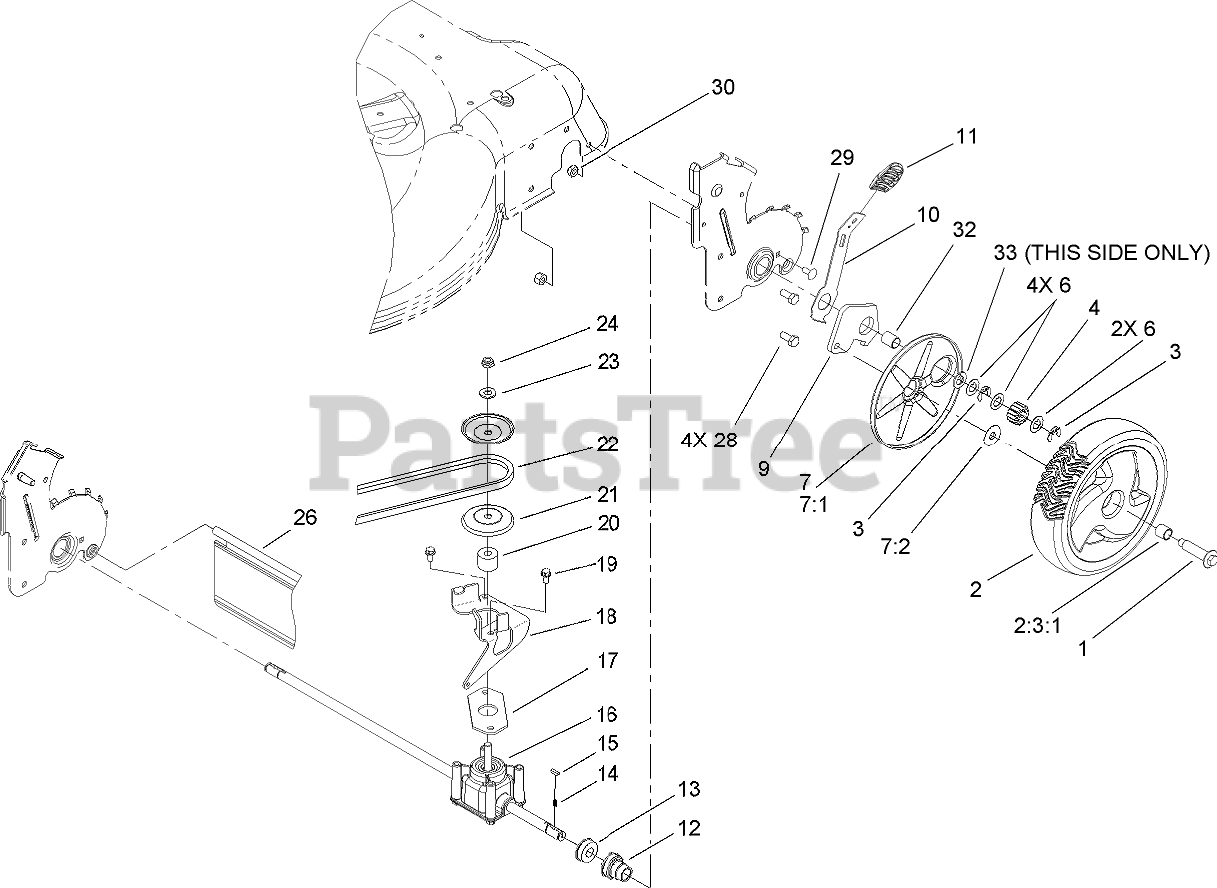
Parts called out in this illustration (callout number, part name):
1	BOLT-SHOULDER
2	Wheel Gear ASM
2:3	Wheel ASM
2:3:1	BUSHING
3	RING-CLIP, LOCKING
4	Gear-Pinion, 15t
6	Washer-Thrust
7	WHEEL COVER ASM
7:1	COVER-WHEEL
7:2	WASHER-STEPPED
9	ARM-PIVOT, REAR
10	ARM-SPRING
11	Knob-Lever, HOC
12	RETAINER-BUSHING, HOC
13	BEARING-BALL
14	SPRING-COMPRESSION
16	TRANSMISSION ASM
17	GASKET-GEARBOX
18	BRACKET-PIVOT
19	SCREW-HWH
20	SPACER
21	PULLEY-HALF
22	BELT-V
23	WASHER-FLAT
24	NUT-HEX
26	SHIELD-TRAILING
28	SCREW-HH
29	SCREW-CARR
30	NUT-LOCK, NI
32	BUSHING-SLEEVE
33	WASHER-THRUST
